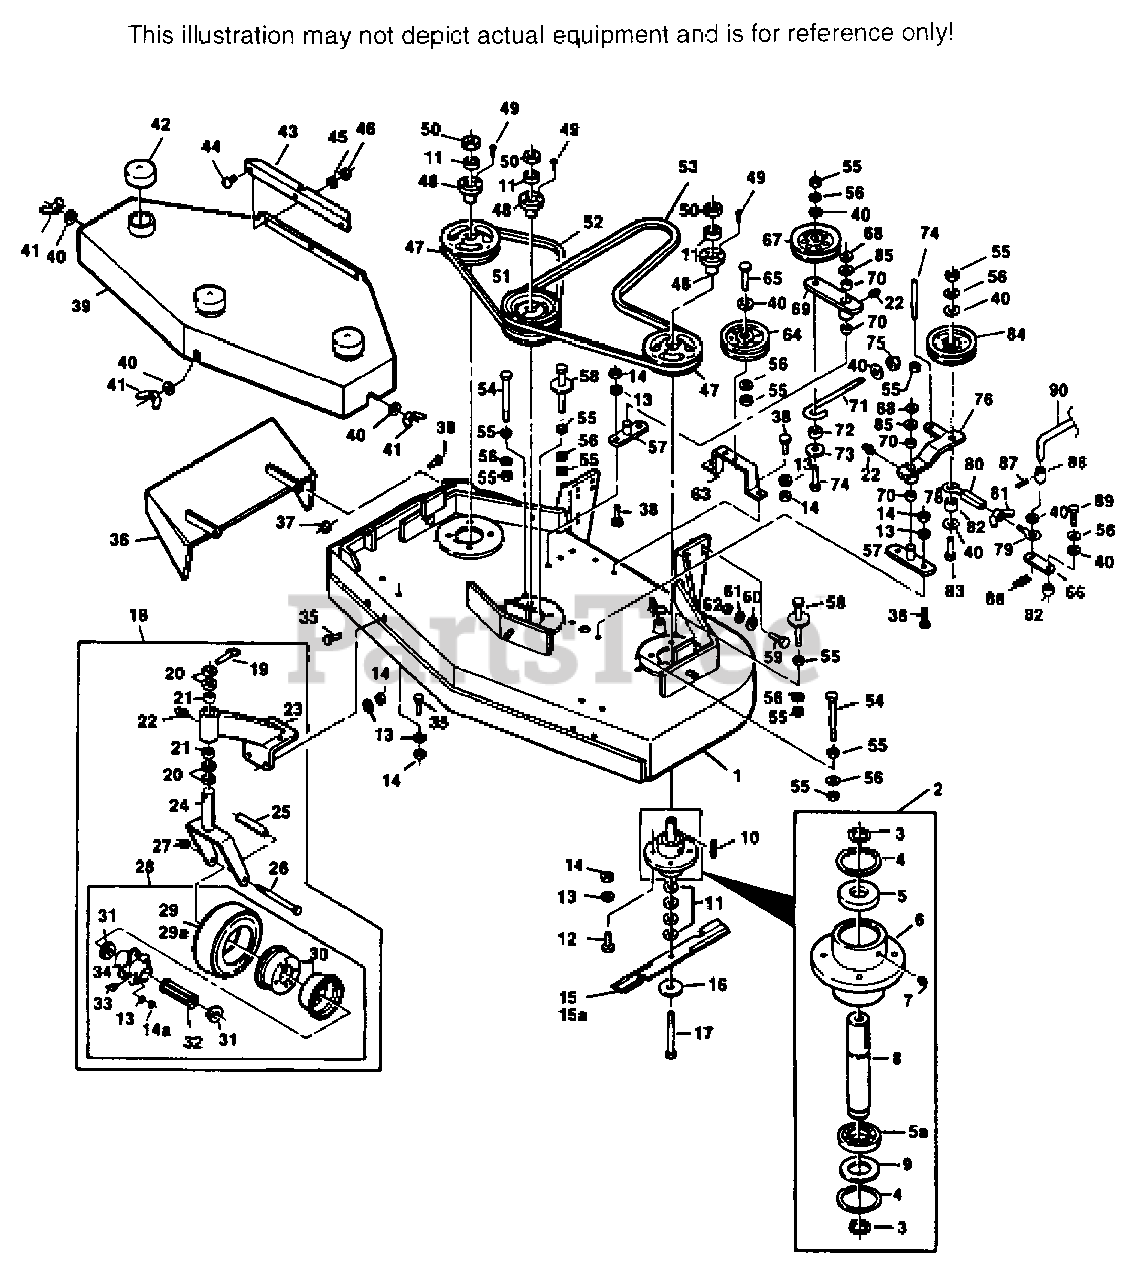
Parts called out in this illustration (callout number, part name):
1	CUTTER DECK WLD(INCL. DECALS)
2	CUTTER SPINDLE ASSY.(INCL. 3-9)
3	RETAINING RING, 1" EXT.-INVERTED
4	RETAINING RING, 2-7/16 INT.-BASIC
5	BEARING, CUTTER SPINDLE UPPER
5A	BEARING, CUTTER SPINDLE LOWER
6	SPINDLE HOUSING
7	GREASE FITTING, STR. 5/16 SERR.
8	SPINDLE, CUTTER BLADE
9	WASHER, 1-15/16 X 2-13/32 X 16 GA.
10	KEY, 1/4 X 1/4 X 2
11	SPACER, CUTTER BLADE
15	CUTTER BLADE, 16-1/2" STD.
15A	CUTTER BLADE, 16-1/2" HIGH LIFT
16	FLAT WASHER, 5/8W
17	HEX HEAD BOLT, 5/8-11 X 9-1/2
18	CASTER ASSY, COMP.(INCL. 19-28)
19	QUICK PIN
20	SPACER, CASTER YOKE, 1/2 LONG
21	BRONZE BEARING
22	GREASE FITTING, STR. 1/4-28
23	SUPPORT ASSY.(INCL. 21-22)
24	CASTER YOKE WLD.
25	SLEEVE, CASTER WHEEL BEARING
26	HEX HEAD BOLT, 1/2-13 X 5-1/2
28	WHEEL ASSY.(INCL. 13-14, 29-34)
29	TIRE ONLY, CASTER WHEEL
29A	INNER TUBE ONLY, CASTER WHEEL
30	RIM PAIR, CASTER WHEEL
31	RETAINER, BEARING, CASTER WHEEL
32	ROLLER BEARING, CASTER WHEEL
33	GREASE FITTING, 45 1/4-28
34	HUB ASSY. W/BOLTS, CASTER WHEEL
36	DISCHARGE CHUTE WLD.
37	HEX NUT, 5/16-18 ELASTIC STOP
39	BELT COVER ASSY.(INCL. DECALS)
40	WASHER, 25/64 X 15/16 X 12 GA.
41	WING NUT, 3/8-16
42	SPINDLE SHIELD
43	BELT COVER SKIRT
47	PULLEY(INCL. 48-49)
48	TAPER HUB
51	PULLEY, DOUBLE(INCL. 48-49)
52	BELT, RH BLADE DRIVE
53	BELT, BLADE DRIVE
57	IDLER PIVOT WLD.
58	BELT GUIDE WLD.
60	WASHER, 15/32 X 59/64 X 16 GA.
62	HEX NUT, 7/16-14, ELASTIC STOP
63	IDLER PULLEY SUPPORT
64	PULLEY, BELT GUIDE
66	CAM LINK
67	IDLER PULLEY, "V" GROOVE
68	RETAINING RING, 3/4 EXT.-"E"69
69	IDLER ARM ASSY.(INCL. 22 & 70)
70	BRONZE BEARING
71	ROD, IDLER PULL, J
72	SPACER, J PULL ROD
73	WASHER, 3/8 X 1-1/2 X 16 GA.
75	HEX NUT, 3/8-16 ELASTIC STOP
76	IDLER ARM ASSY.(INCL. 22 & 70)
78	EYEBOLT, LH
79	EYEBOLT, RH
80	TURNBUCKLE
81	WING NUT, 5/16-18
82	SLEEVE, CAM CLUTCH
84	IDLER PULLEY, BELT CLUTCH
85	WASHER 49/64 X 1 1/4 X 16 GA.
86	SLEEVE, CLUTCH ROD
